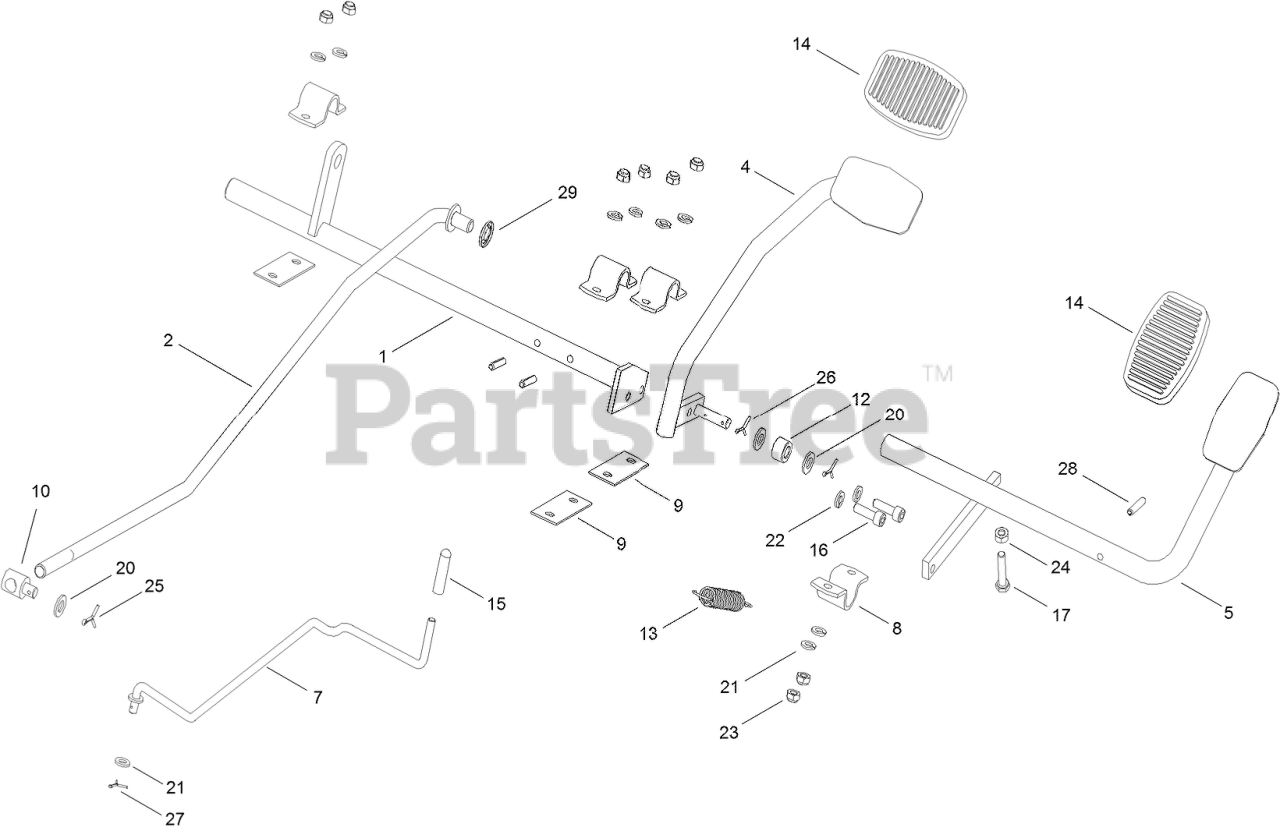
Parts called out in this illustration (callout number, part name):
1	SHAFT-PIVOT
2	ROD-LINKAGE
4	PEDAL-TRAVEL, FORWARD
5	PEDAL-TRAVEL, REVERSE
7	ROD-LEVER, BYPASS
9	SPACER
12	Roller
13	SPRING
14	PAD-PEDAL
15	CAP-BYPASS LEVER, HYDRO
17	SCREW-HH
20	WASHER-PLAIN
21	WASHER
22	WASHER-SPRING
23	NUT-LOCK
24	NUT-HEX
25	PIN-COTTER
26	PIN-COTTER
27	PIN-COTTER
28	PIN-SPRING
29	WASHER-M10
